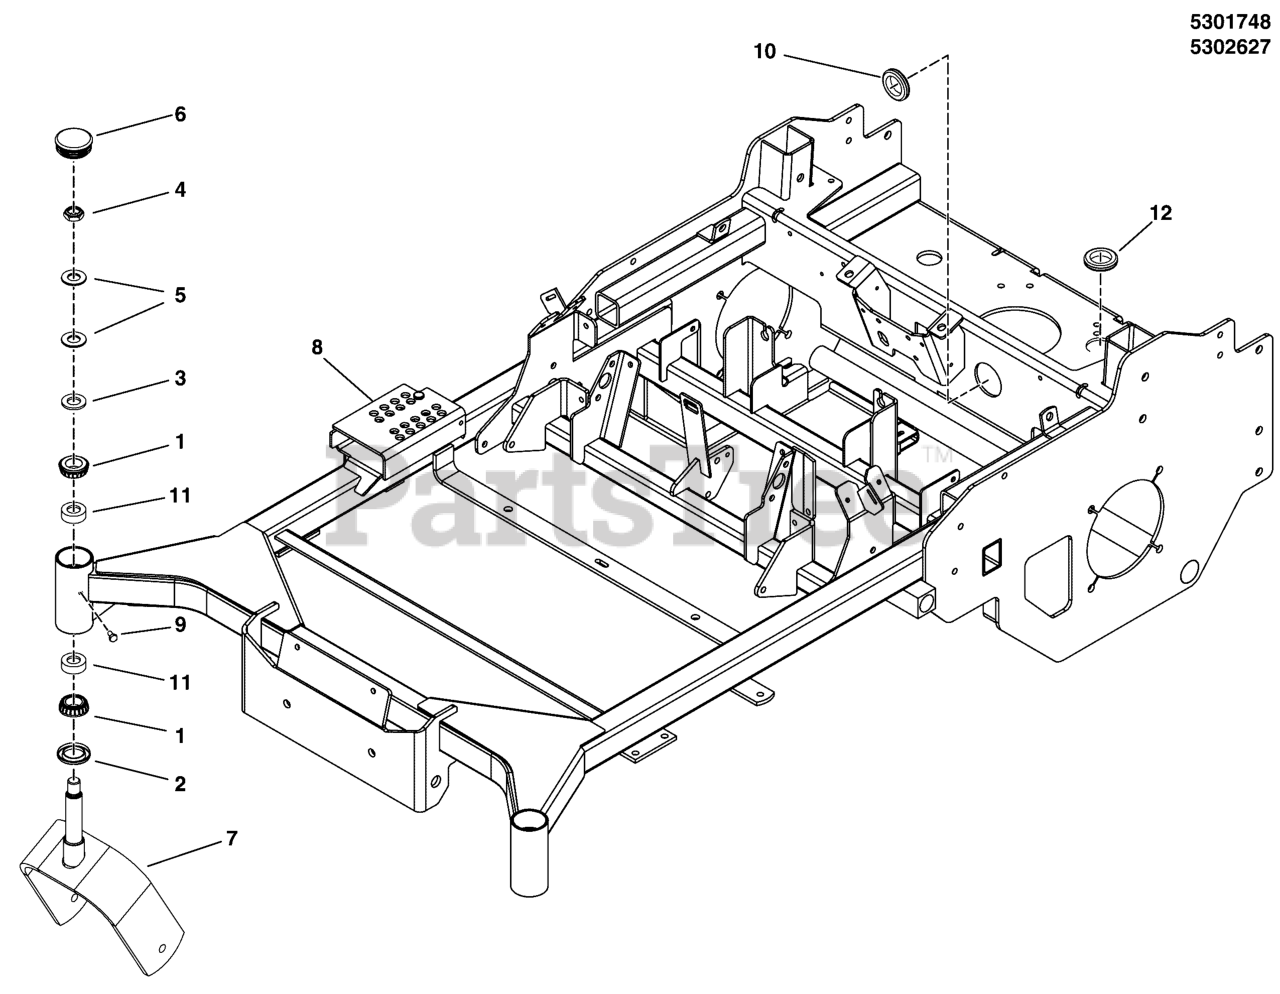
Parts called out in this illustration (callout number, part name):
1	BEARING, TAPERED ROLLER
2	SEAL, GREASE
3	WASHER, 3/4 SAE
4	NUT, 3/4-16, HEX JAM NYLON LOCK
5	WASHER, BELLEVILLE - 1.500 X .755
6	CAP, GREASE, LOW PROFILE
7	WELD, CASTER YOKE - RED
8	* WELD, FRAME - RED
9	BOLT, 1/4-28 X 1/2, GD5 YZ
10	GROMMET, 2" ID
11	CUP, BEARING (SV)
12	GROMMET, 7/8"ID, 1/4" THICK STK
